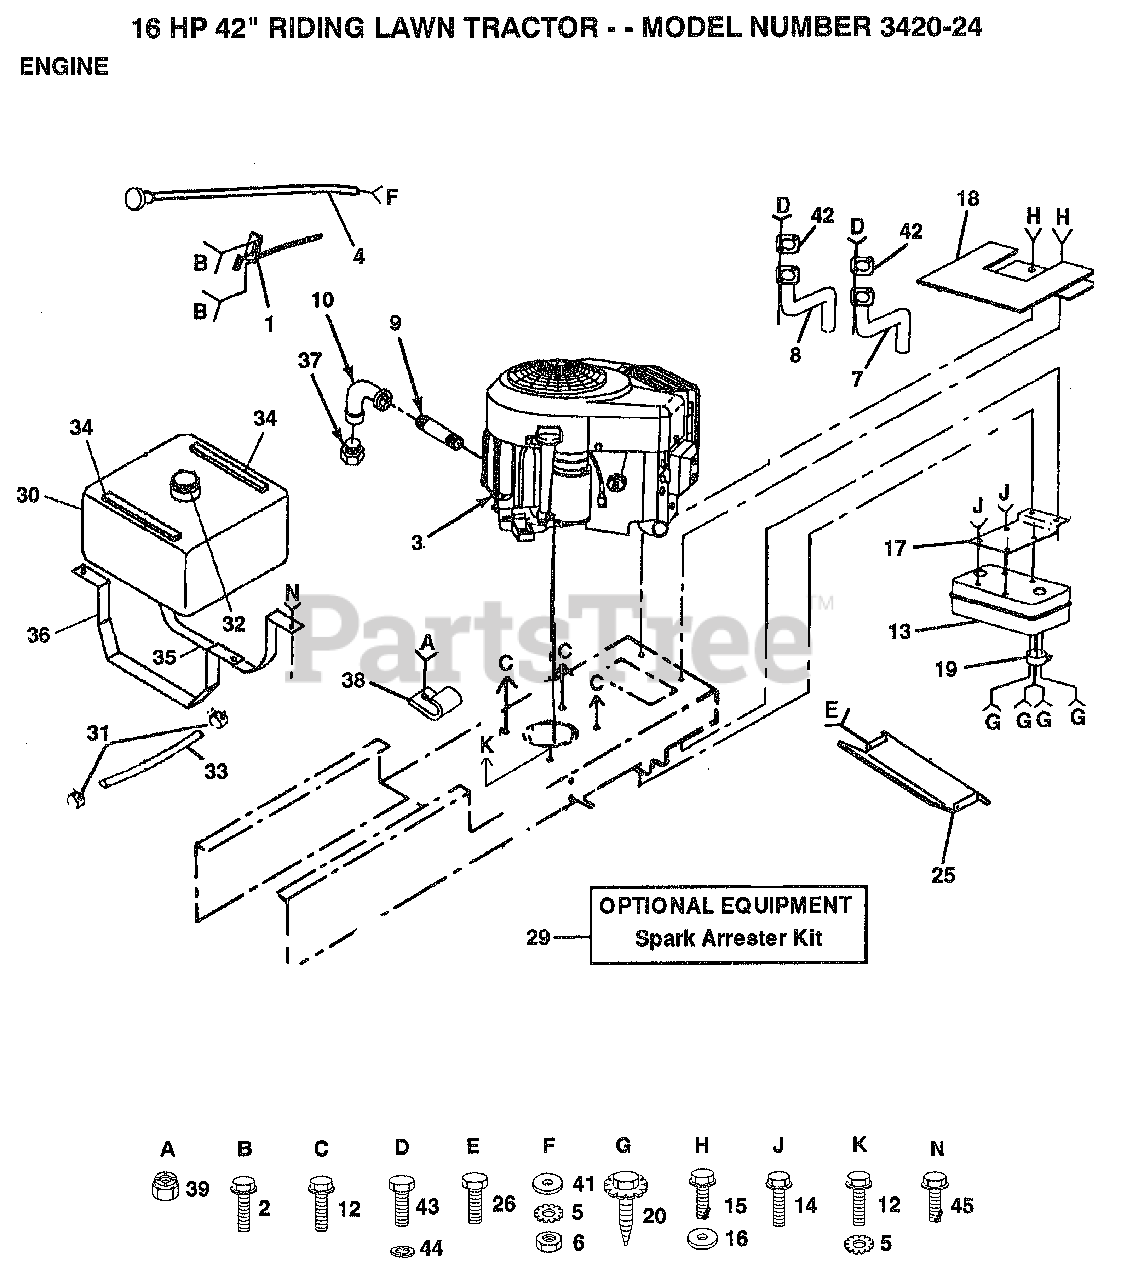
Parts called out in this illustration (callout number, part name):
2	SCREW LT
4	CHOKE CONTROL
5	LOCKWASHER
9	PIPE NIPPLE LT
10	ELBOW
12	SCREW LT
14	SCREW ST
15	SCREW
16	WASHER
17	BRACKET MUFFLER
19	DEFLECTOR.222573
25	HEAT SHIELD
26	SCREW
31	HOSE CLAMP
32	"ARM,SHIFT"
34	"STRIP,FORM"
35	"STRAP,TANK "
36	"STRAP,TANK"
38	CLIP T
41	WASHER
44	LOCKWASHER
45	SCREW LT
